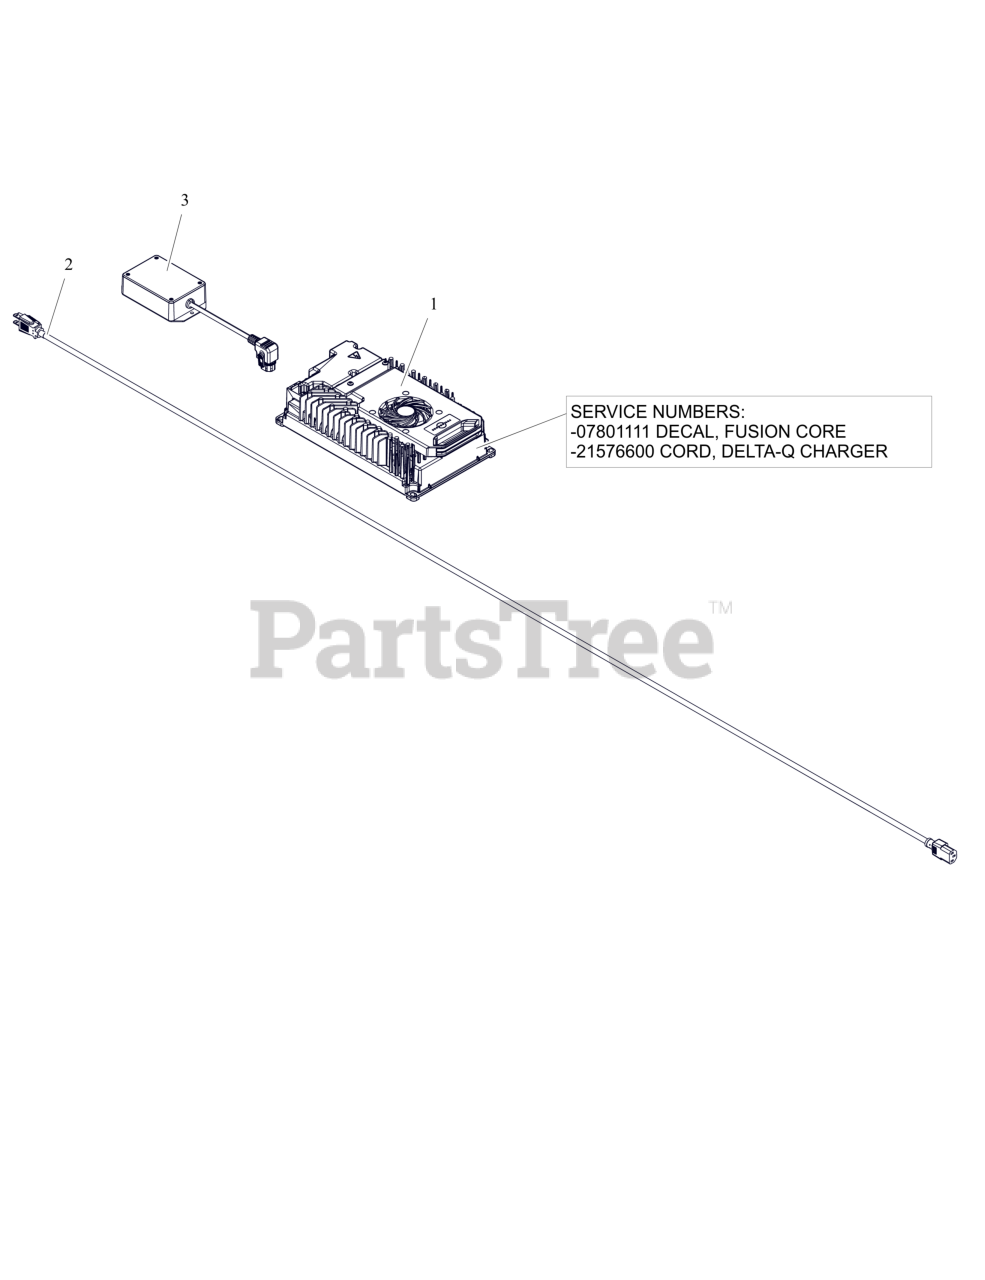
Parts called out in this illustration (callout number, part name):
1	CHARGER, BATTERY DELTA-Q
1	DECAL, FUSION CORE
1	CORD, DELTA-Q Charger
2	CORD, POWER US 120V AC
3	FILTER ,EMI, 120/250V,50-60HZ
